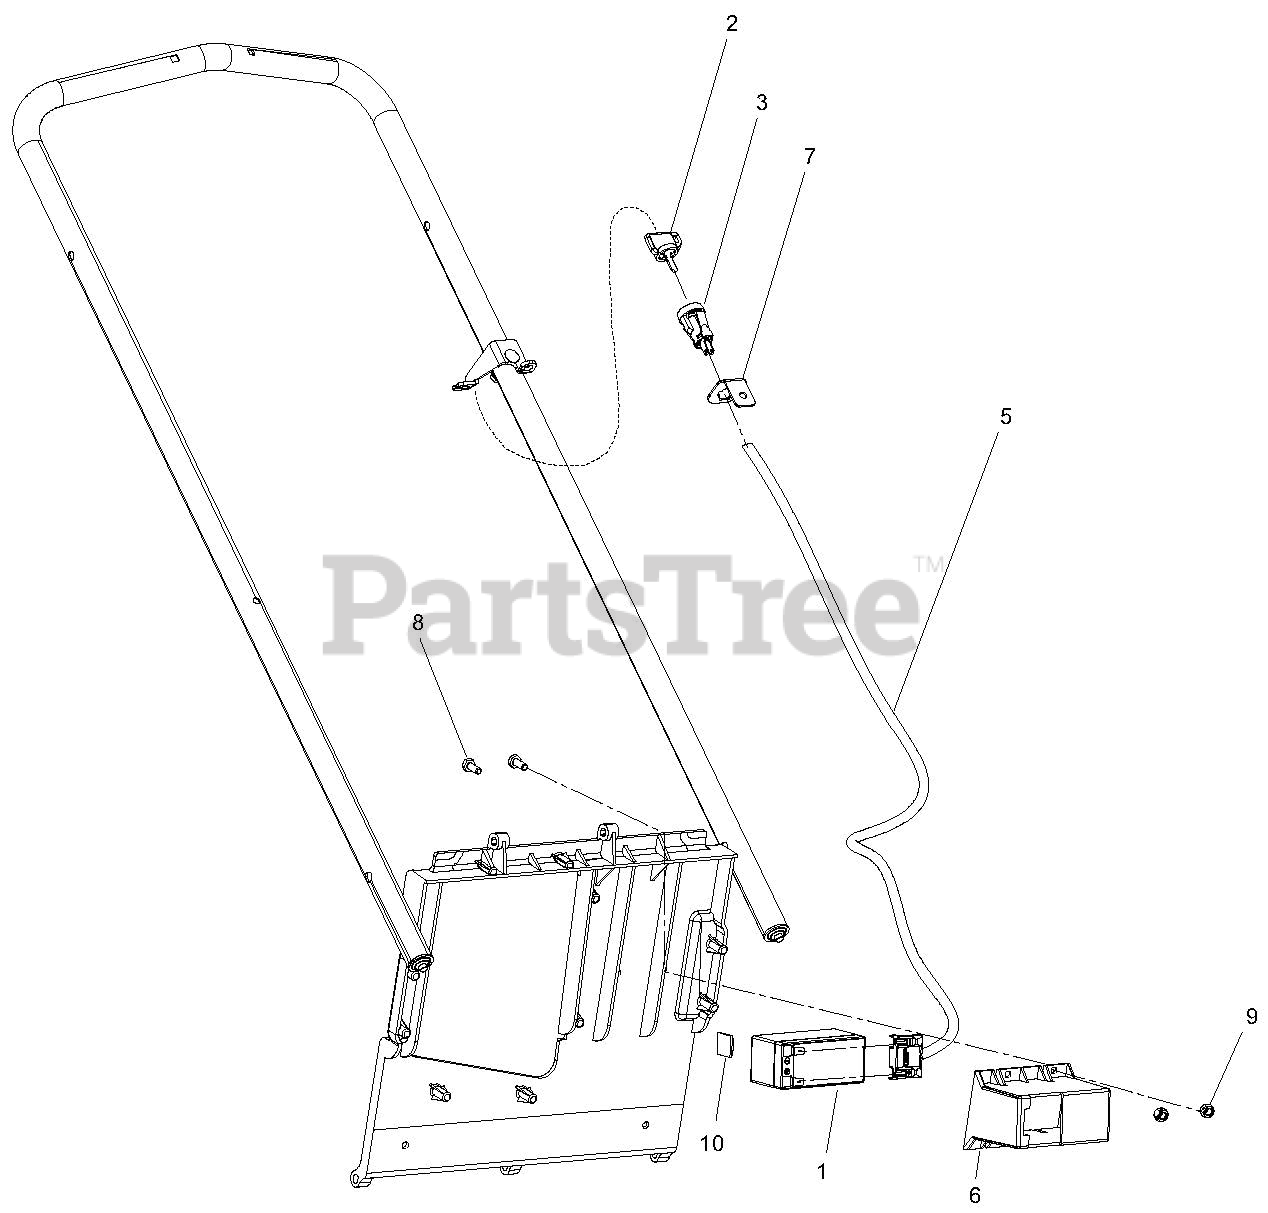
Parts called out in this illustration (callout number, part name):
1	BATTERY,LM(SEE BULLETIN B2117)
2	KEYS, IGNITION
3	SWITCH, KEY
5	HARNESS, ELEC START - LONCIN
6	COVER, BATTERY
7	BRKT, KEY SWITCH
8	BLT-HEX .25-20X.63 GR5 YWZC
9	@NUT-LK-CTR .25-20 YWZC
